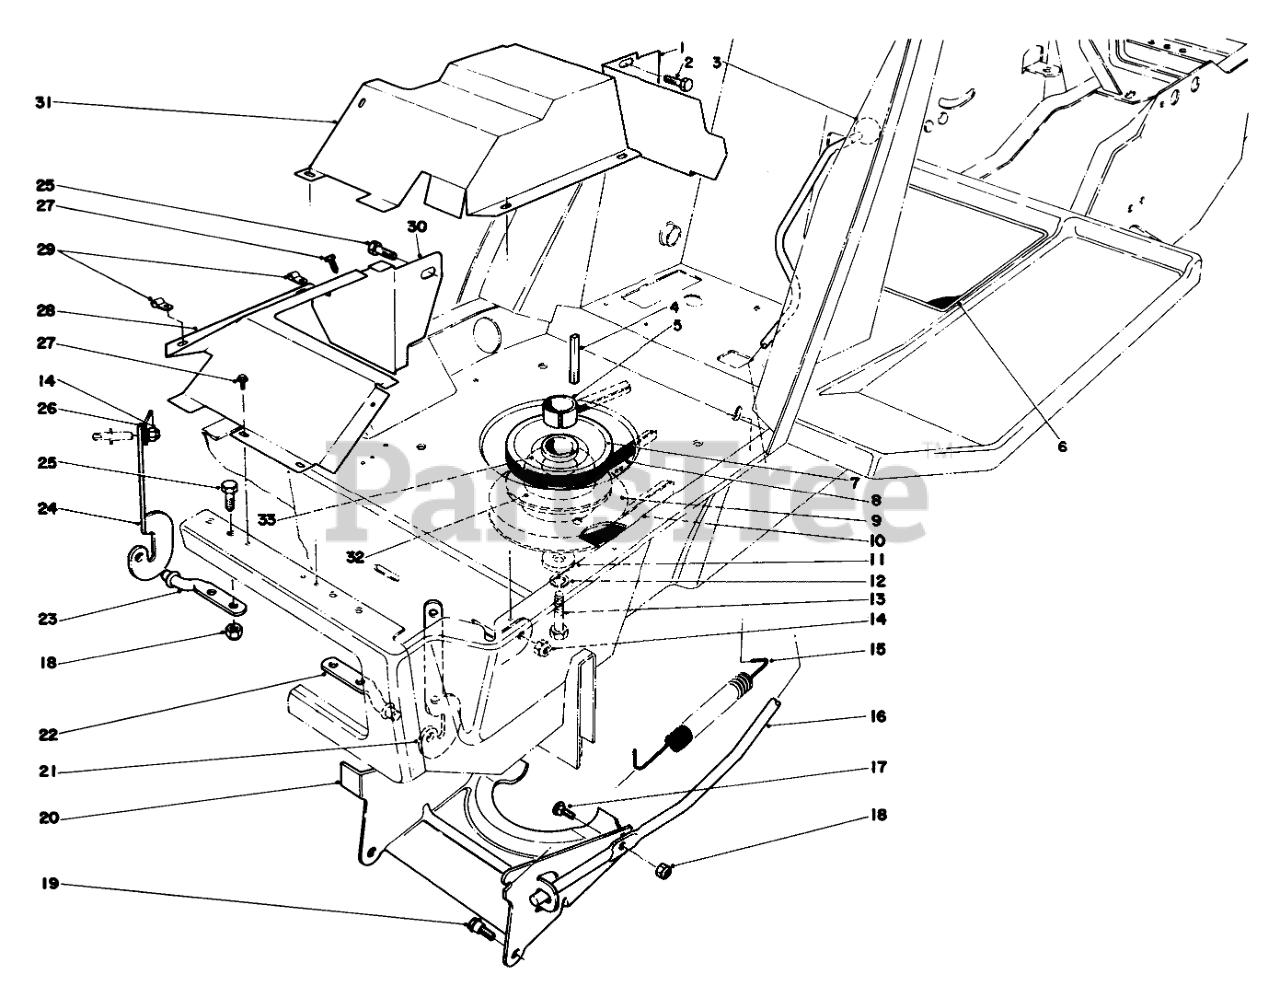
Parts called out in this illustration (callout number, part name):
1	EXH SHIELD SUPT B
2	SCREW-HH
4	KEY-SQUARE
5	PULLEY SPACER
6	OPERATION DECAL
7	TOP SHEAVE
8	V BELT
9	Clutch & Brake-Deck (Incl. Ref. #32 & 33)
10	V BELT
11	WASHER
12	WASHER-LOCK
13	SCREW-HH
14	NUT-LOCK, CONE
15	TRACTION SPRING
16	Engagement Lever
17	Bolt
18	NUT-LOCK, CONE
19	SCREW-SHOULDER
20	CLUTCH ACTUATOR R
21	L.H. HINGE BRACKET
22	LH HOOD HINGE PIN
23	RH HOOD HINGE PIN
24	RH HINGE BRKT
25	SCREW-HH
26	SCREEN SUPT BRKT
27	SCREW-HWHTF
28	Heat Shield
29	CABLE CLAMP
30	Support Heat Shield
31	HEAT SHIELD WA B
32	CLUTCH PLATTER
33	SPRING WASHER
